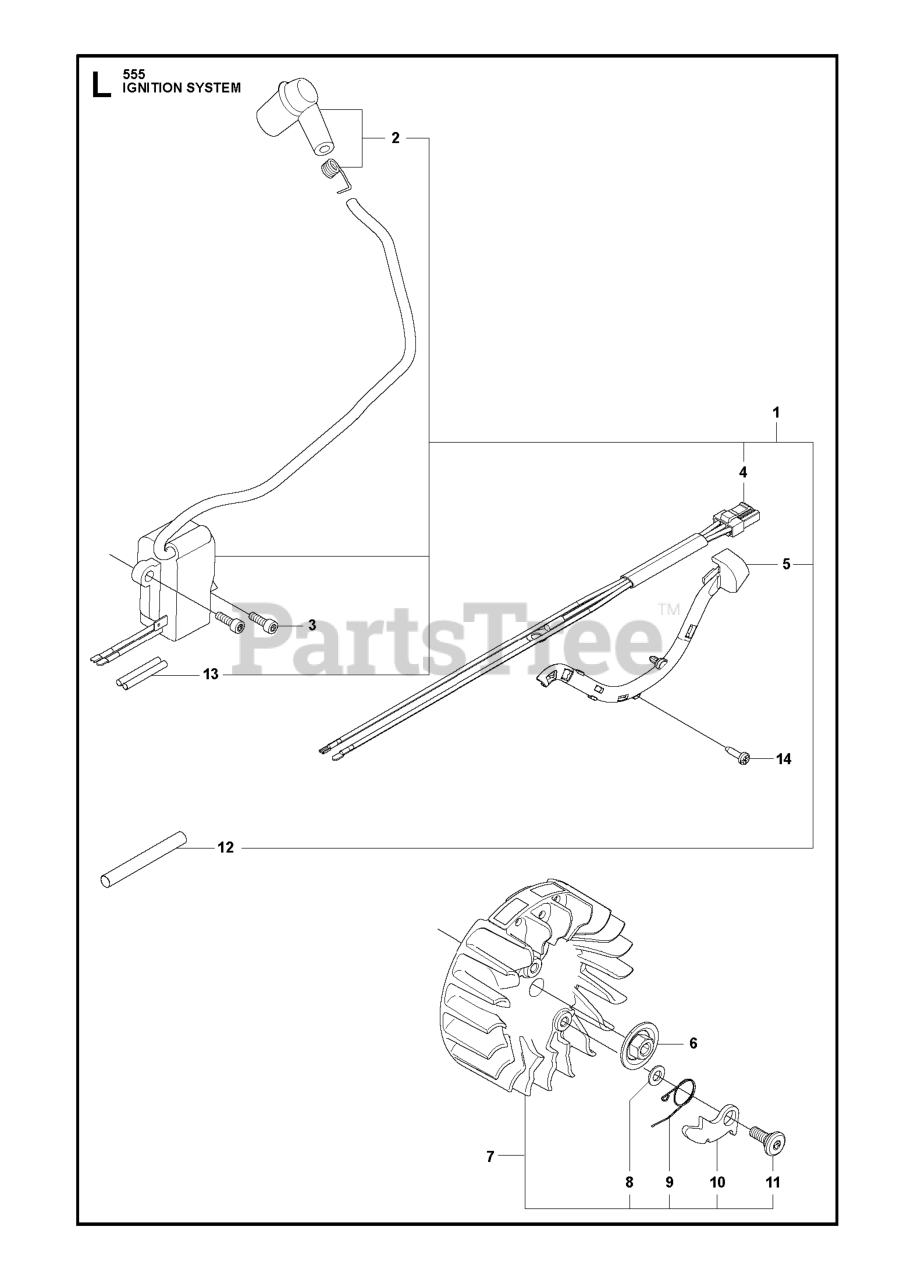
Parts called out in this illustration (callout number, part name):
1	IGNITION MODULE ASSY 555 REV
1	IGNITION MODULE ASSY
2	SPARK PLUG CAP ASSY
3	SCREW ITXSCFM
4	WIRING ASSY
5	CABLE HOLDER
6	NUT,M8X1PP A/F13X6,8XØ30X4X1,5
7	FLYWHEEL ASSY
11	SCREW
12	CABLE COVER
13	SHRINK HOSE
14	SCREW CITXPANT
